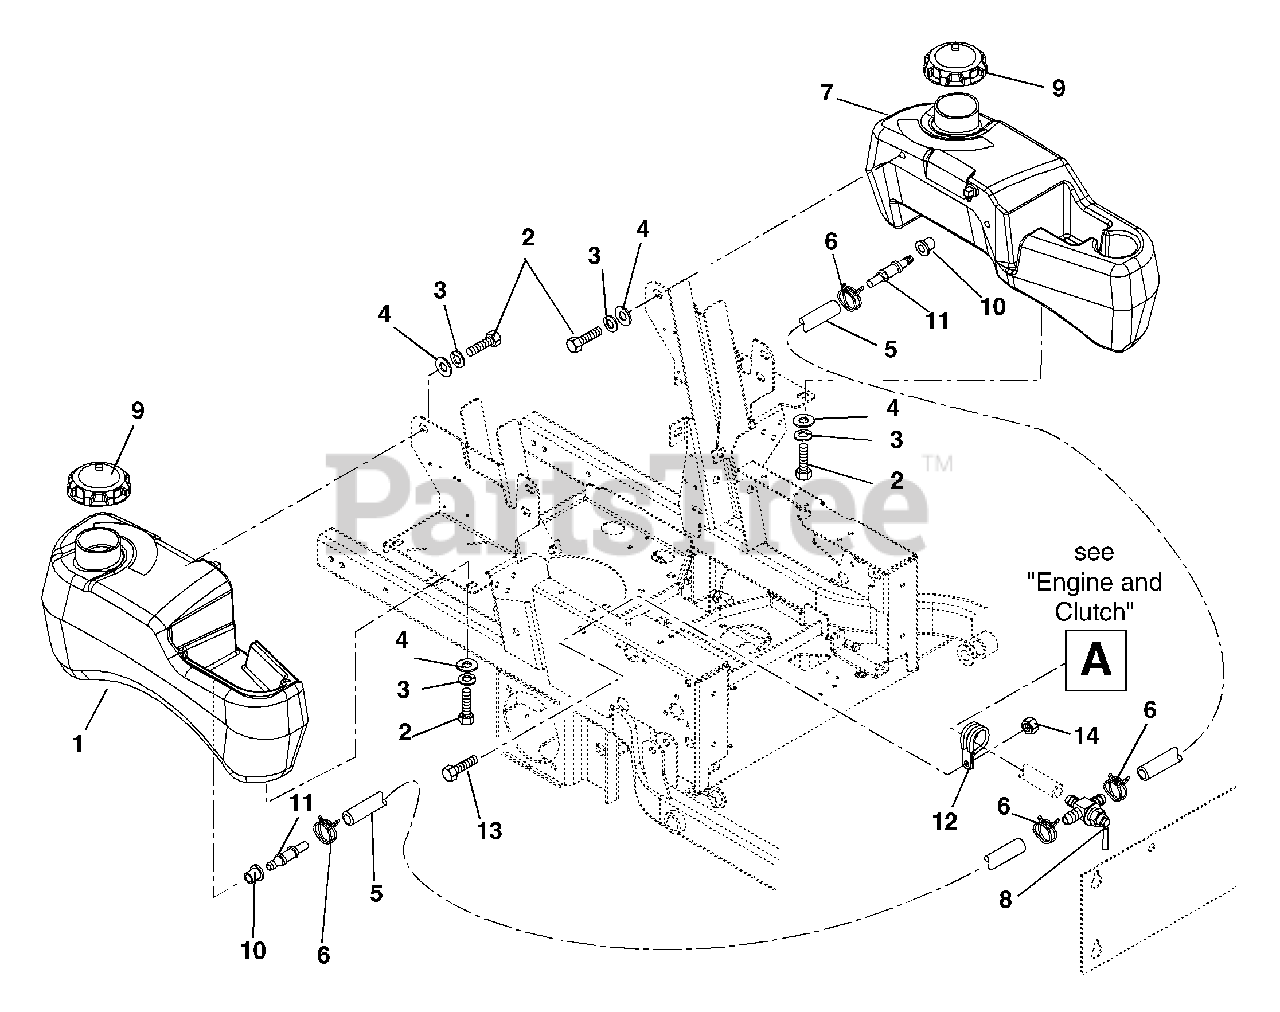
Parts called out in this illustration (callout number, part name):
1	TANK, GAS - RH W/O HOSE
2	@BLT-HEX .31-18X.75 GR5 YWZC
3	@WSHR-LK .31X.078 REG YWZC
4	@WSHR-FL-STL.38X.875X.083 YWZC
5	GAS LINE-BULK 1/4" I.D.
6	CLAMP-HOSE WIRE .490/.510X.116
7	TANK, GAS - LH
8	VALVE, FUEL
9	CAP - FUEL
10	BSHG-FLG .375 X 1.062 X .625 R
11	FITTING, TANK
12	CLAMP, CUSHIONED STEEL
13	@BLT-HEX .38-16X1.00 GR5 YWZC
14	@NUT-LK-TOP-FLG .38-16 YWZC
